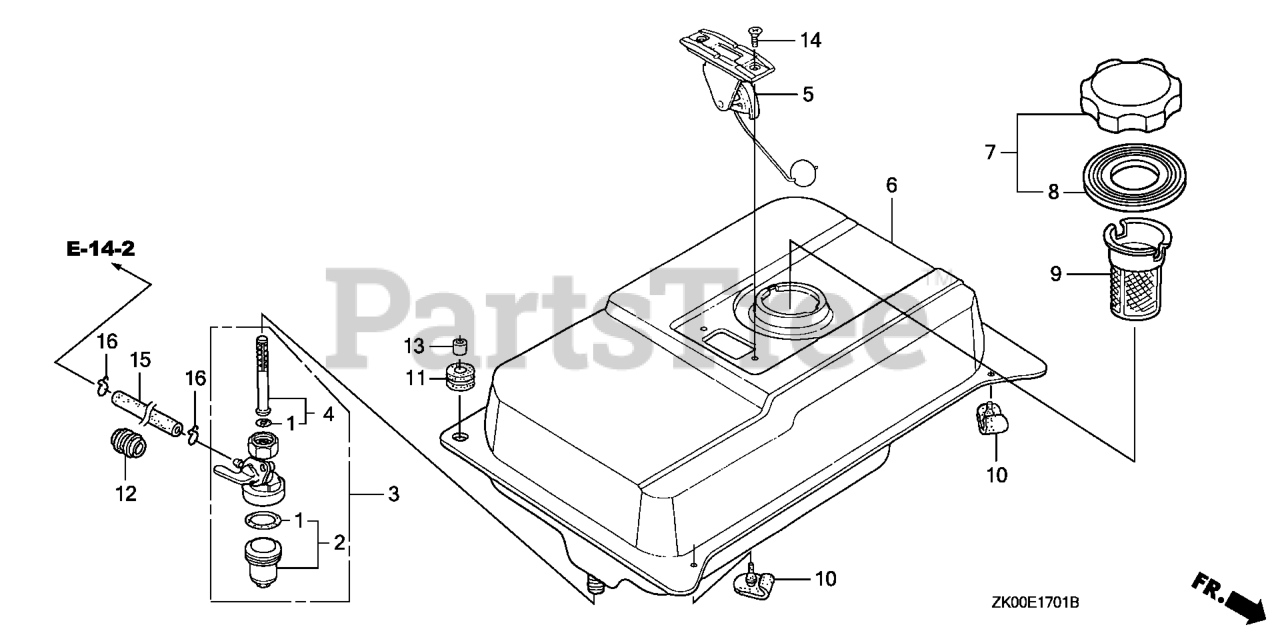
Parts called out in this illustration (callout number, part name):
1	GASKET SET, PETCOCK (CONTAINS 1 LARGE & 1 SMALL. USE AS NEEDED)
2	CUP, FUEL STRAINER
3	PETCOCK ASSY.
4	SCREEN SET
12	RUBBER, FUEL (9X15X20)
15	BULK HOSE, FUEL (4.5X3000) (Honda Code 5137104). (4.5X140)
16	CLIP, TUBE (B8)
